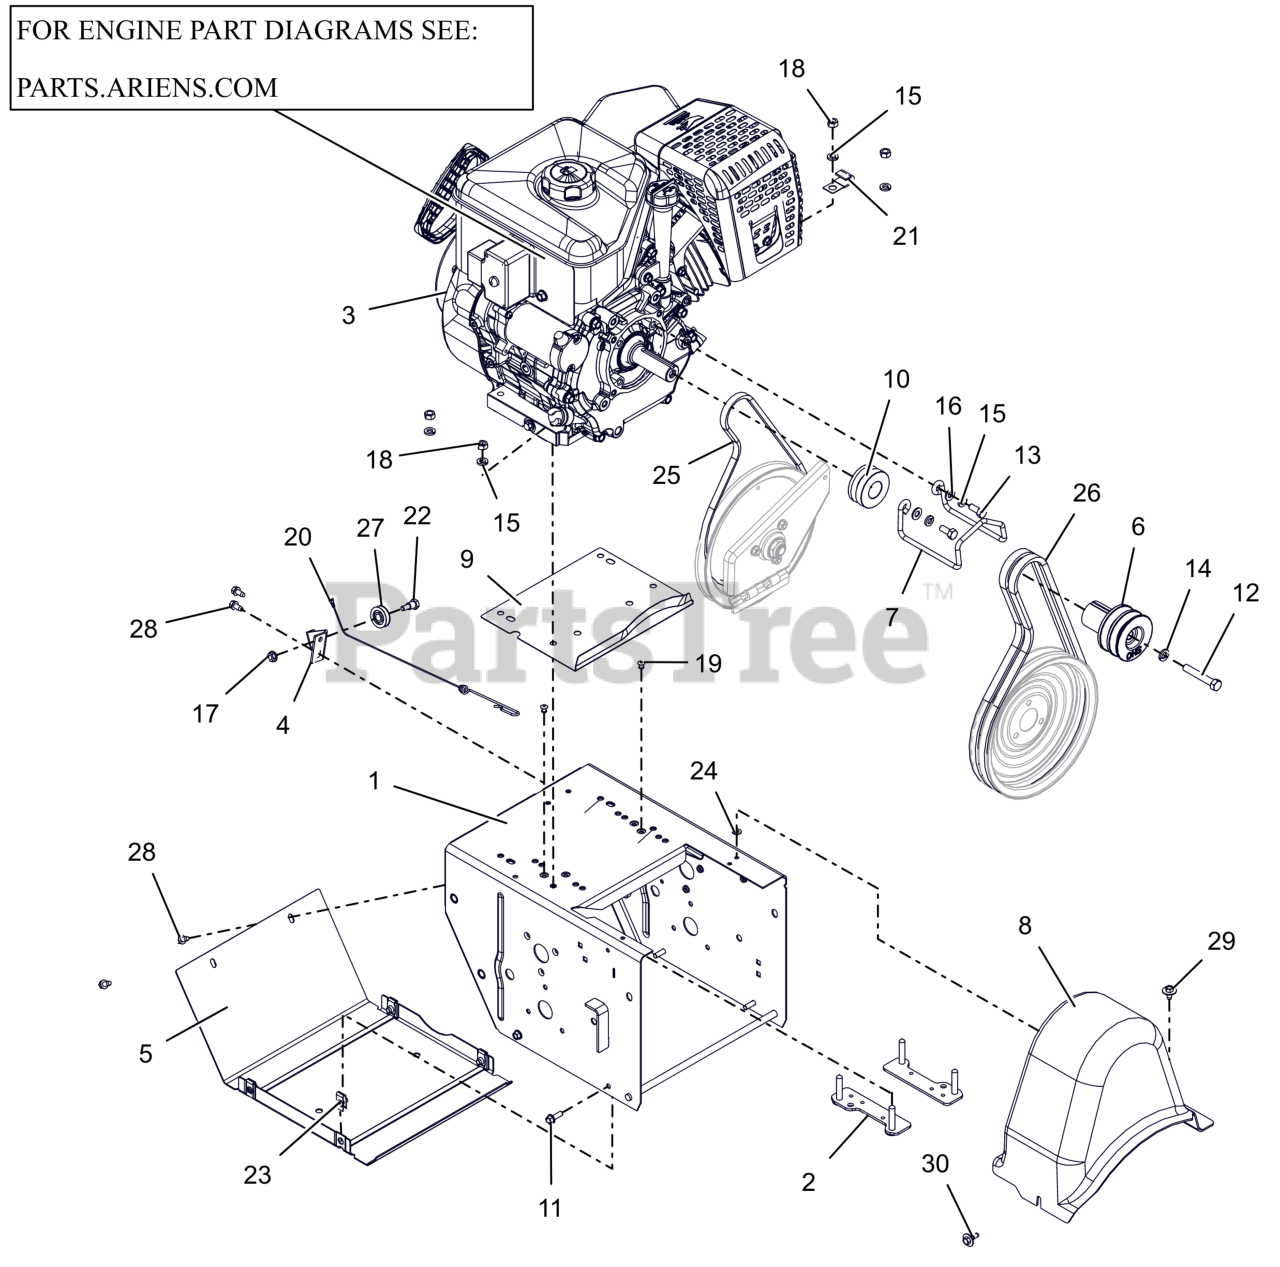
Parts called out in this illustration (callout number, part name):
1	FRAME, MAIN - 14GA DELUXE (ORANGE)
2	STRAP, BOLT-LARGE
3	ENGINE, EFI 369 GEN 3 240V/60W
4	BRACKET, CABLE PULLEY
5	COVER, BOTTOM
6	SHEAVE,ATTACHMENT-SHO 2 GRV
7	FINGER, BELT
8	COVER, BELT-LARGE
9	BAFFLE, WATER - LARGE BLOCK
10	SHEAVE, TRACTION (KEYLESS)
11	BLT, HWH .25-20X.75 G5 ZCC
12	BLT, HEX .38-24X2.25 G5 ZCC
13	BLT, HEX .31-24X.750 G5 ZCC
14	WSHR,LK-REG .375X.094 ZCC
15	WSHR, LK-HVY .312X.097 ZCC
16	WSHR,FLT .344X.688X.065 ZCC
17	NUT-LK-TOP-FLG .250-20 GF ZCC
18	NUT, HEX .312-18 ZCC
19	RVT, POP .1875 ZCC
20	CABLE, LOWER TRACTION,SS & PRO
21	J-CLAMP
22	BOLT, SHLDR -.375 X .375 X .25-20
23	NUT-RTNR .25-20X.56
24	NUT-PUSH .25X.50 O.D.
25	V-BELT, 3L-WRAPPED
26	V-BELT, HA-RAW EDGE (SET)
27	PULLEY, CABLE
28	SCR-TAP .25-20X.50 HWH ZCC
29	SCR, TAP .25-20X.50 LG HWH ZCC
30	SCR-TAP .25-20X.5 CAPTIVE
